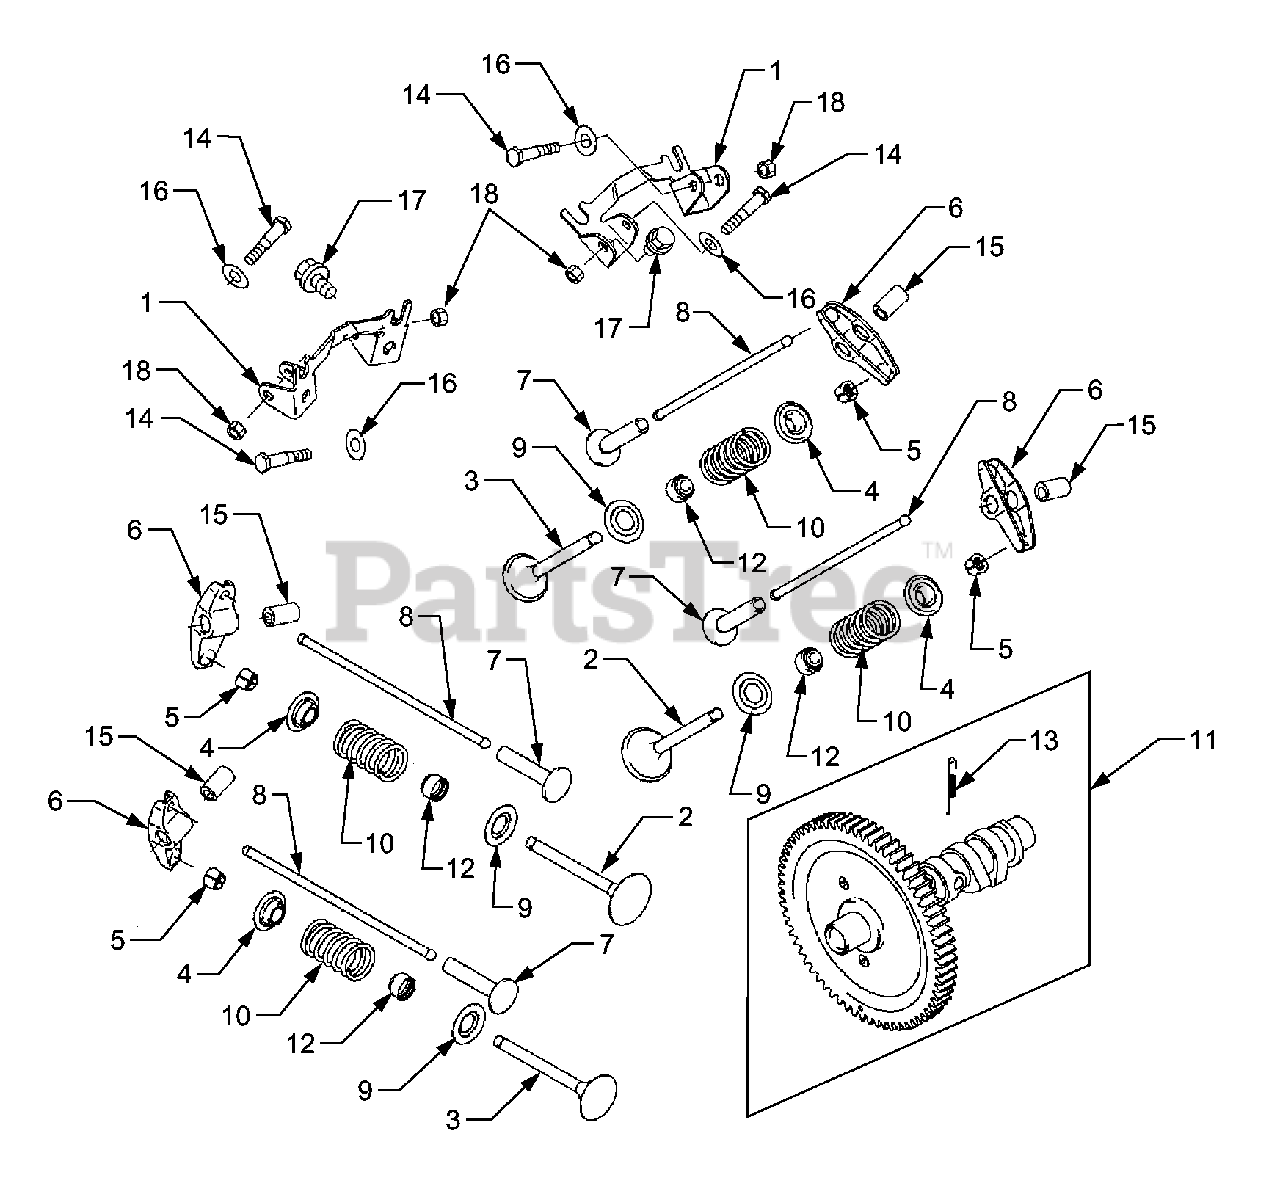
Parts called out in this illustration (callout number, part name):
2	Valve, Intake
3	Valve, Exhaust
4	Retainer, Valve Spring
6	Arm, Rocker
10	Spring, Valve
16	Washer, 8.1 x 18 x .5
17	Bolt, Flanged
18	Nut, Hex
